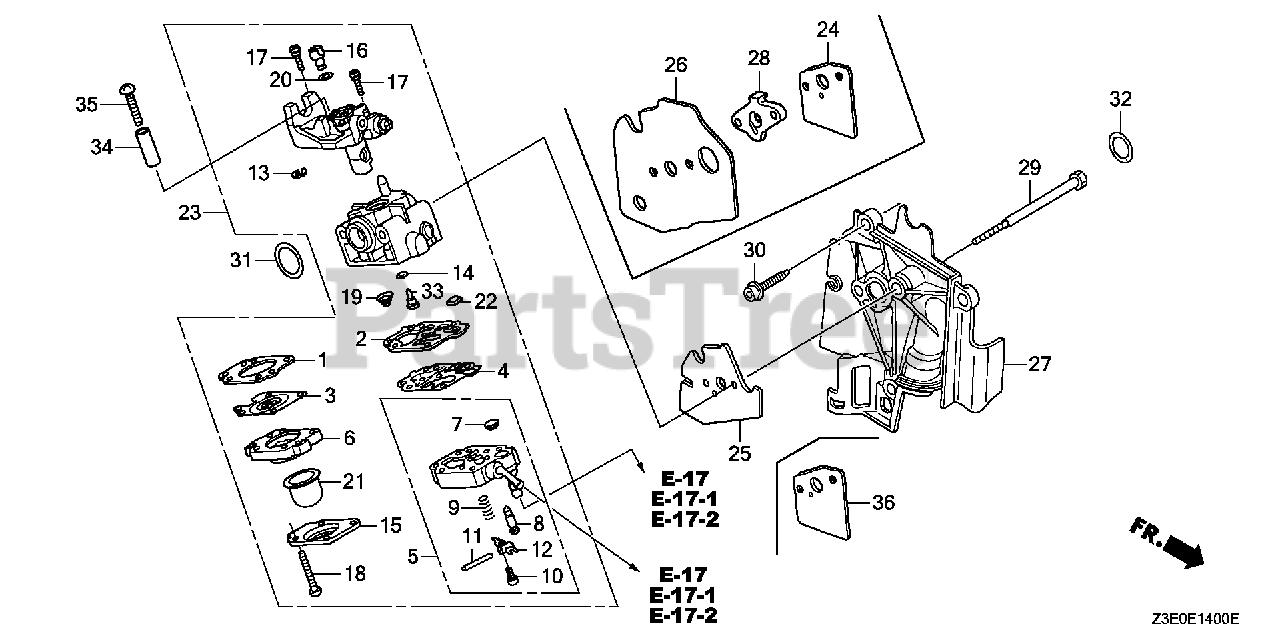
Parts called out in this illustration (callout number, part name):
1	GASKET, METERING DIAPHRAGM
2	GASKET, PUMP
3	DIAPHRAGM ASSY., METERING
4	DIAPHRAGM, PUMP
5	BODY ASSY., PUMP (CARBURETOR NO.)
6	BODY ASSY., AIR PURGE
7	SCREEN, INLET
8	VALVE, INLET NEEDLE
9	SPRING, METERING LEVER
10	SCREW, METERING LEVER PIN
11	PIN, METERING LEVER
12	LEVER, METERING
13	RING, RETAINING
15	COVER, PRIMER PUMP
17	SCREW, THROTTLE COLLAR
18	SCREW, PUMP COVER
19	SPRING, PUMP
21	PUMP, PRIMER
22	FILTER, FUEL INLET
23	CARBURETOR ASSY. (WYB 7E)
25	GASKET, CARBURETOR
29	BOLT (5X53)
30	BOLT, SOCKET (5X16)
31	O-RING (14.8X2.4)
32	O-RING (12.3X2.4)
33	JET (#33)
33	JET (#34) (CARBURETOR NO.)
33	JET (#35) (CARBURETOR NO.)
